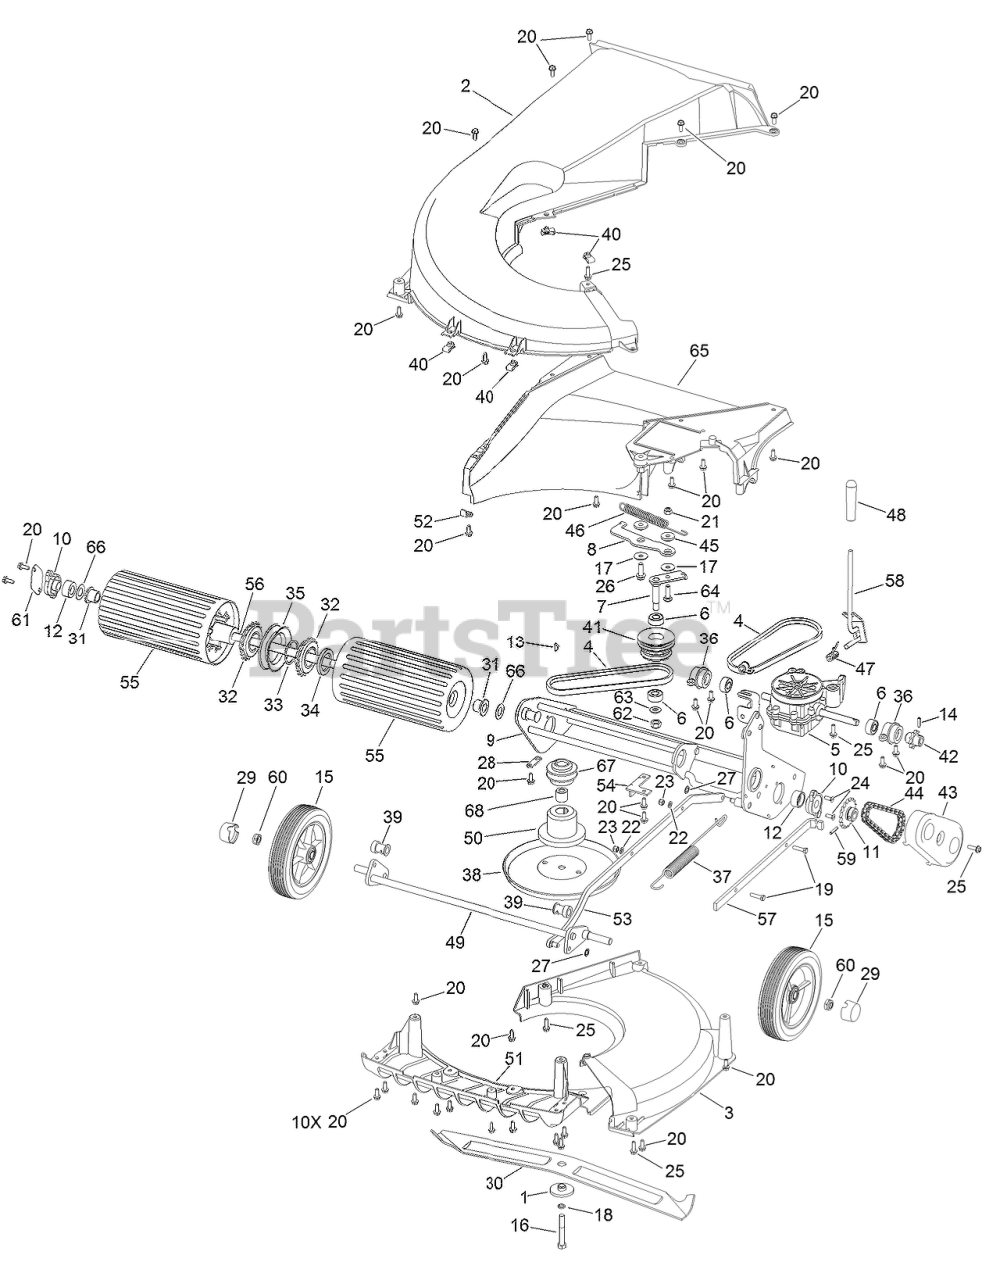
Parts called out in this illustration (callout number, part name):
1	SPACER-DISTANCE, CUTTERBAR
2	UNDERDECK-FIXED
3	UNDERDECK-REMOVABLE
4	BELT-VARIATOR (520)
5	GEARBOX ASM
6	BEARING
7	LEVER TAKE-UP ASM
8	ARM-PLATE, TAKE-UP
9	FRAME-ROLLER, REAR
10	BEARING-ROLLER
11	SPROCKET-18T
12	COVER-DUST, BUSHING
13	KEY-WOODRUFF
14	PIN-ROLL
15	WHEEL-RIBBED
16	BOLT-UNF
17	WASHER-PLAIN
18	WASHER-SPRING
19	SCREW-HH
20	SCREW-TAPTITE
21	NUT-HEX, NI
22	WASHER-PLAIN
23	NUT-NYLOC
24	SCREW-TAPTITE
25	SCREW-TAPTITE
26	SCREW-TAPTITE
27	WASHER-STARLOCK
28	PLATE-SECURING
29	CAP-HUB
30	CUTTERBAR
31	BUSHING-ROLLER, OILITE
32	FREEWHEEL-ROLLER
33	SPACER-STEEL
34	LOCKNUT
35	SHROUD-FREEWHEEL
36	HOUSING-PIVOT BEARING, LH
37	SPRING-COUNTER BALANCE
38	DISC-FRICTION
39	BEARING-AXLE, FRONT
41	PULLEY TAKE-UP
42	SPROCKET-GEARBOX
43	COVER-DRIVE
44	CHAIN-40 PITCHES (3/8 INCH LINK)
45	BUSHING-PIVOT
46	SPRING-VARIATOR
47	SPRING-TORSION, HOC
48	KNOB-HOC
49	AXLE-FRONT
50	BOSS-BLADE
51	FINS-FRONT
52	CLAMP
53	ROD-CONNECTING
54	BRACKET-ROD
55	ROLLER-REAR
56	SHAFT-ROLLER
57	BAR-TENSION, SPRING
58	LEVER-HOC
59	PIN-SPRING, SELLOC
60	NUT-UNF
61	PLATE-COVER, DUST
62	NUT-HEX, NI
63	WASHER-PLAIN
64	SCREW-HH
65	THROWPLATE
66	WASHER
67	PULLEY
68	SPACER-BOSS
